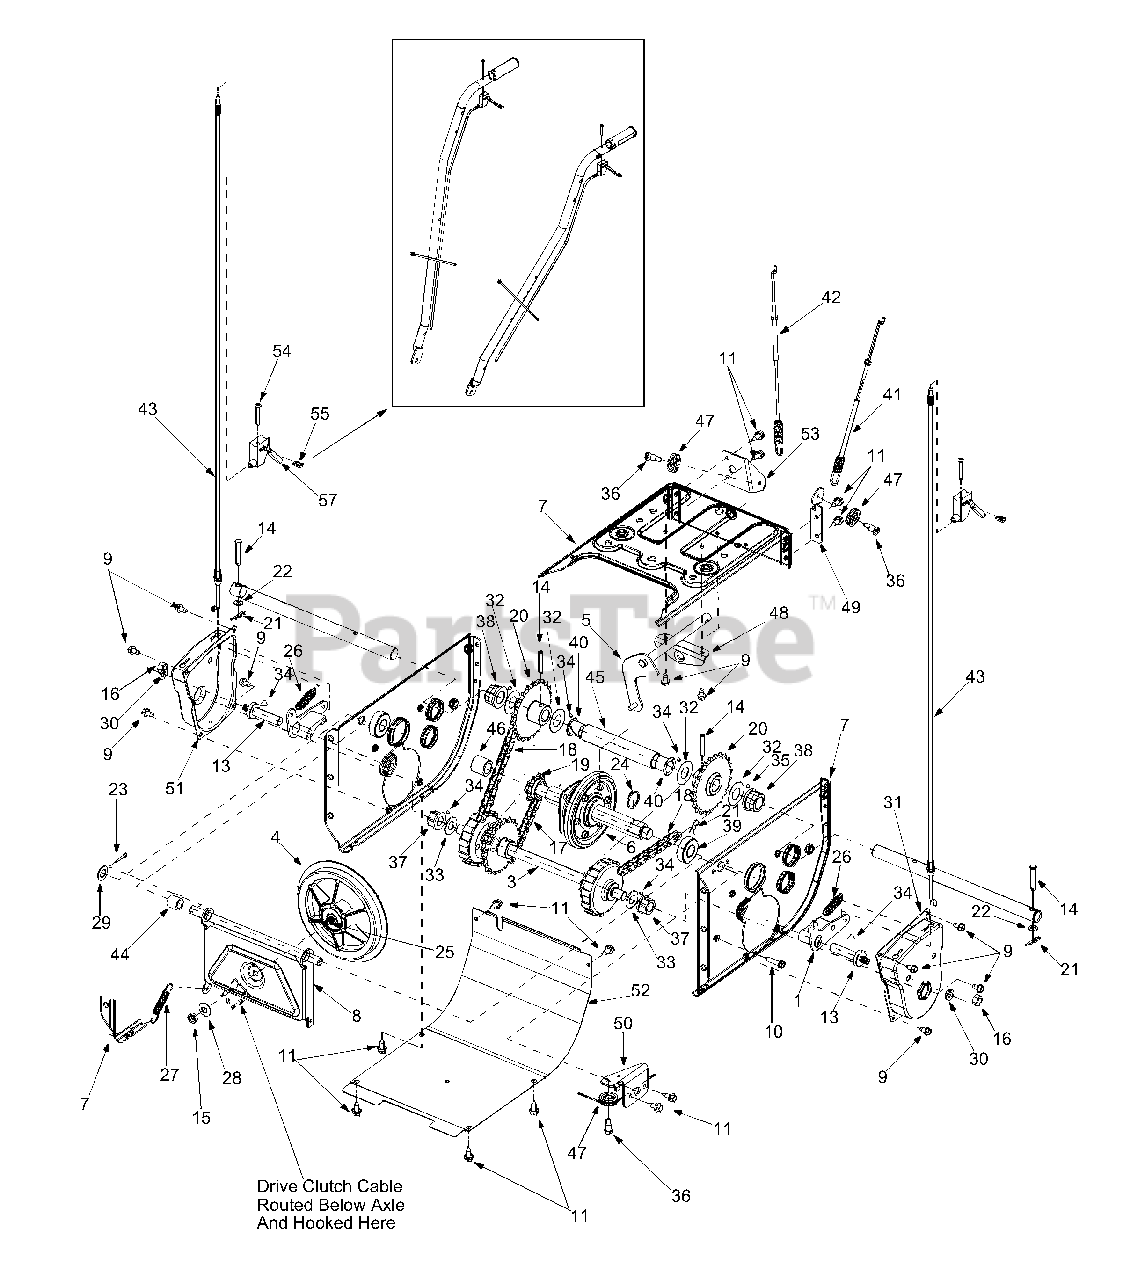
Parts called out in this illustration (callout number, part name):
1	Dogg Assembly: RH
2	Dogg Assembly: LH
3	Shift Assembly: Steerable Drive
4	Friction Wheel Disc Assy.
6	Wheel Assembly, Friction
10	Hex Washer Screw 1/4-20 x 1
11	Hex Screw 1/4-20 x .625"
13	Actuator Shaft
15	Jam Nut 3/8-24 Gr.8
16	Hex Nut: 3/8-16
19	Sprocket: 10T
25	Adhesive: Loctite(R)
26	Extension Spring
27	Extension Spring
34	Lubricant
35	Grease
36	Shoulder Screw
37	Hex Flange Bearing
38	Hex Flange Bearing
39	Ball Bearing
40	Flange Bushing
41	Auger Clutch Cable
42	Drive Clutch Cable
43	Steering Cable
45	Axle Support Tube
47	Roller Cable
57	Turn Trigger
